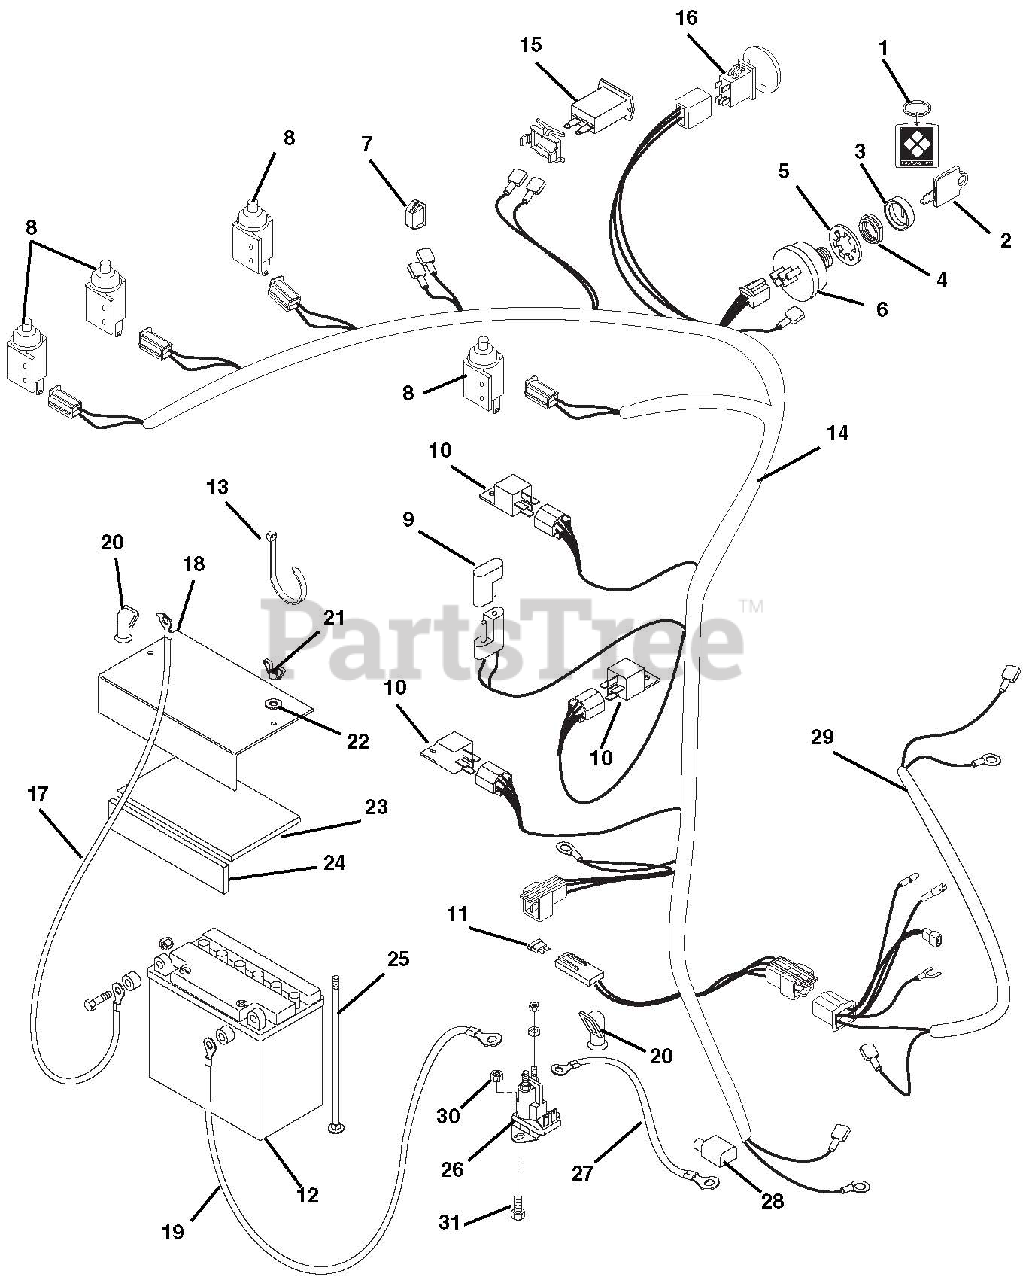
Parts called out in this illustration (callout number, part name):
1	Key Chain
2	Ignition Switch Key
3	Cap, Ignition Switch
4	Nut, Panel .625-32
5	Washer-Lock .625 Internal Tooth
6	Key Switch
7	Light, Indicator
8	Single-Pole N.O. with Cover
9	Molded Diode Plug-Clear 1 AMP
10	Relay
11	Fuse-30 AMP
12	Battery, 12 Volt
13	Tie Wrap-Black
14	Wire Harness, Pro-300
15	Hour Meter
16	Switch, Clutch With Retainer
17	Cable, Negative Battery
18	Cover-Battery
19	Cable-Battery
20	Boot, Insulator
21	Nut-Locking-Wing .25-20
22	Washer-Flat-Steel .281 x .625 x .065
23	Pad, Battery
24	Pad, Battery
25	Bolt-Round Head Square Neck .25-20 x 7.00 Grade 2
26	Solenoid
27	Cable, Starter 6.75"
28	Boot, Starter Terminal Red
29	Adapter, Wire Harness
30	Nut-Locking-Center .25-20
31	Bolt-Hex .25-20 x .50 Grade 5
